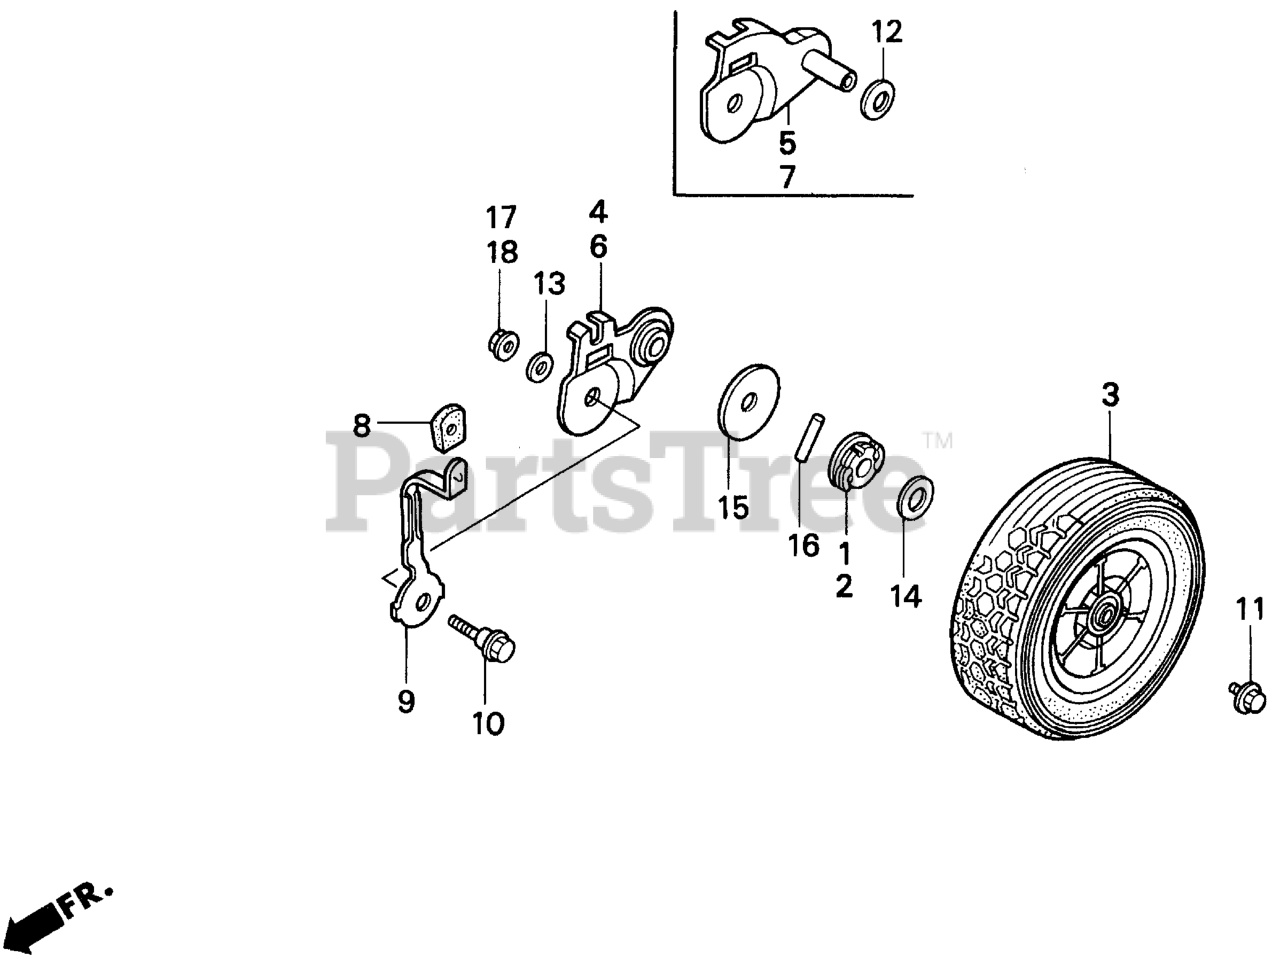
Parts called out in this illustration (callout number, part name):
1	HOLDER, R. RATCHET
2	HOLDER, L. RATCHET
3	WHEEL, PROPELLED (8") (NH31)
4	ARM C, L. WHEEL ADJUSTER
6	ARM D, R. WHEEL ADJUSTER
8	GRIP, ADJUSTER
9	PLATE, RR. ADJUSTER
10	BOLT, ADJUSTING CENTER
11	BOLT, WHEEL
13	WASHER A, HANDLE HOLDER SETTING
14	WASHER (16MM)
15	WASHER, WHEEL
16	ROLLER (5X23.8)
18	NUT, FLANGE (8MM)
NI	TIRE (8 INCH)
